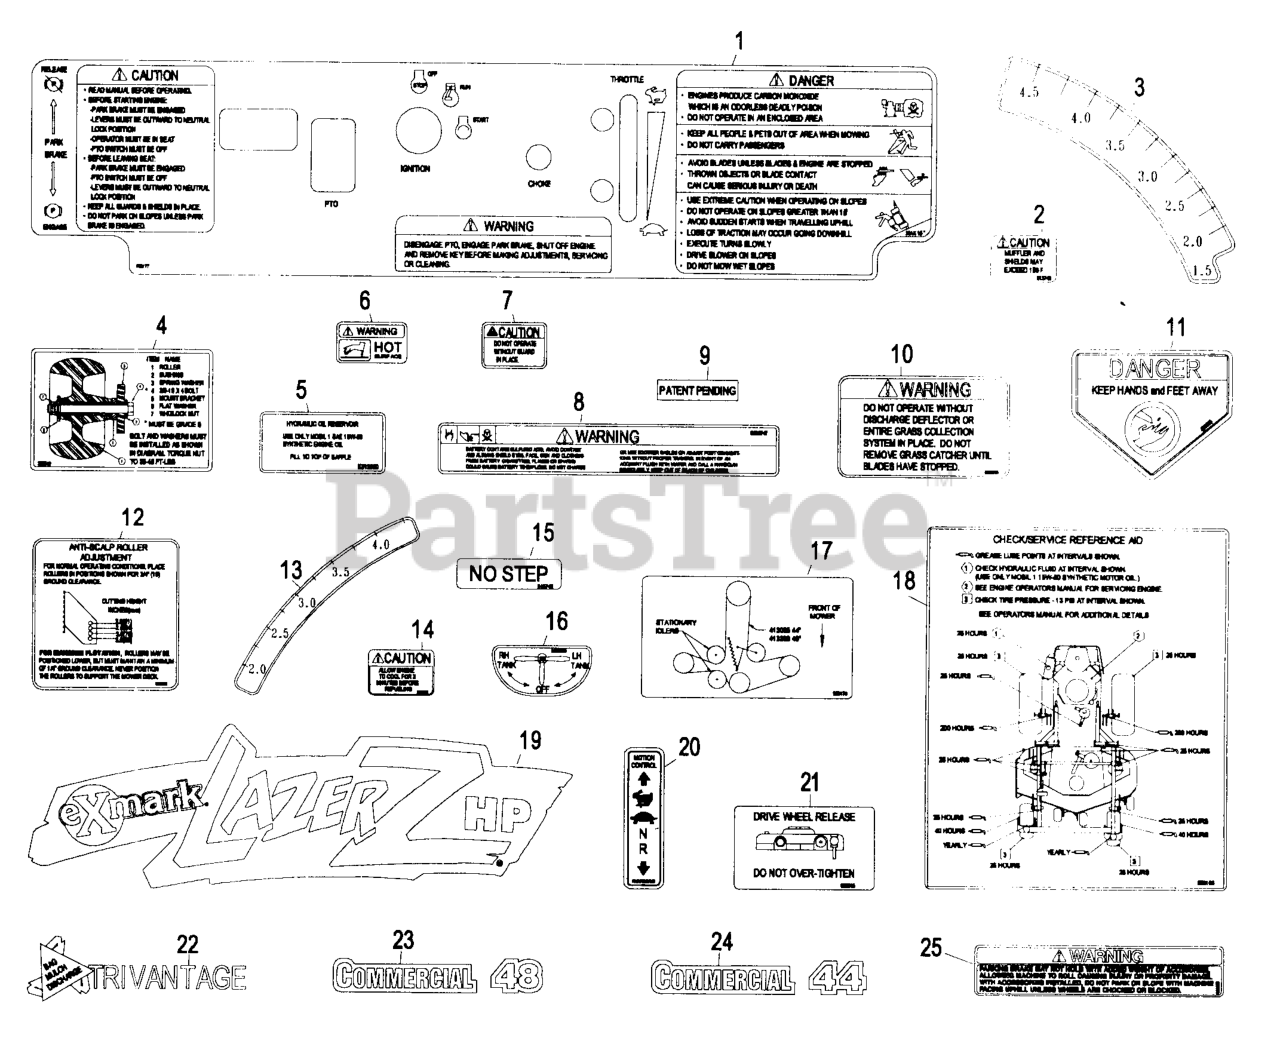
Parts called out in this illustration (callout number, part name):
3	DECAL-DECK HEIGHT, OUTER
4	DECAL,ROLLER MOUNTING
5	DECAL,HYD TANK
7	DECAL-GUARD
8	DECAL-BATTERY
9	Decal, Patent Pending
10	DECAL-WARNING, DISCHARGE
11	DECAL-DANGER
12	DECAL,ANTISCALP
13	DECAL-DECK HEIGHT, INNER
15	DECAL,NO STEP
17	Decal, Belt Routing
21	DECAL,DRIVE RELEASE
23	DECAL,COMMERCIAL 48
24	DECAL,COMMERCIAL 44
25	DECAL,PARK BRAKE WARNING
